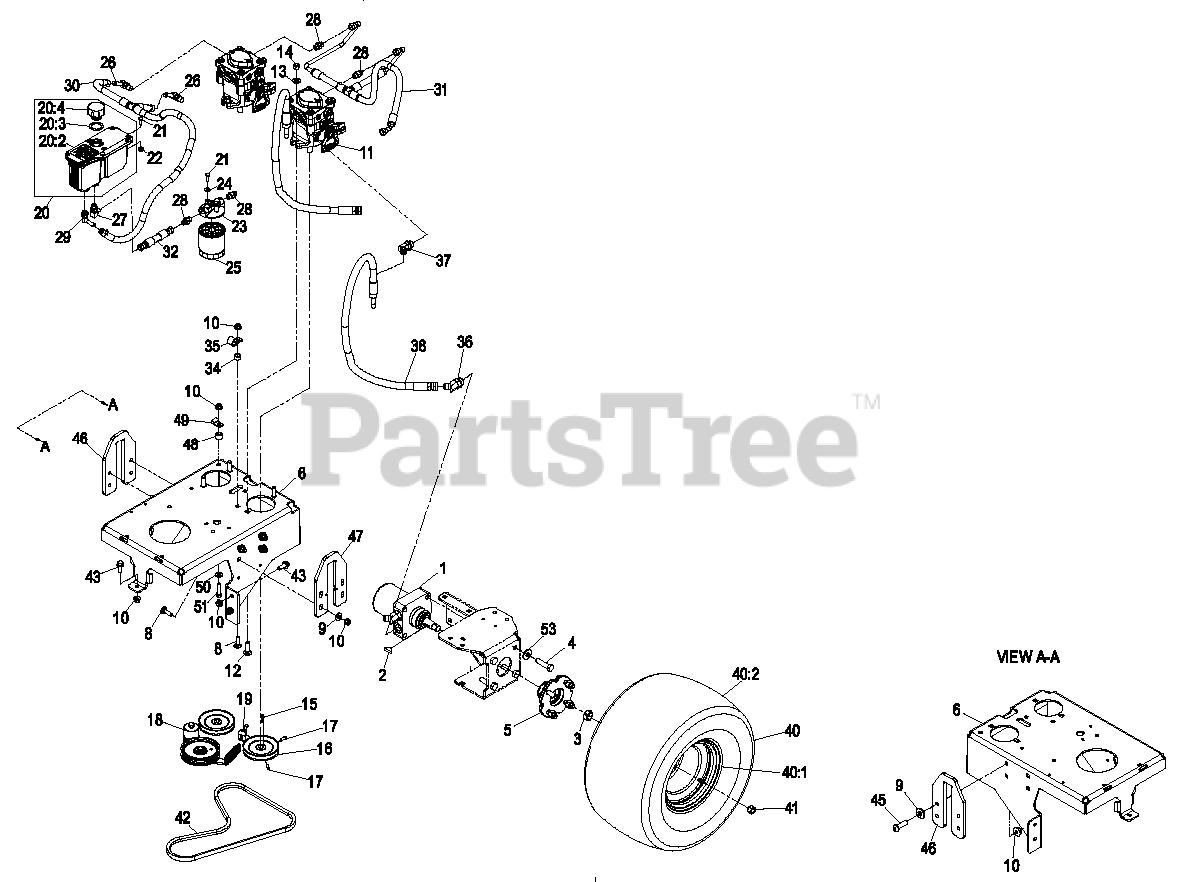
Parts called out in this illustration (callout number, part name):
1	HYD MOTOR ASM
2	KEY-WOODRUFF
3	NUT-MOTOR, WHEEL
4	SCREW-HH
5	WHEEL HUB ASM
6	BASE-ENGINE
8	BOLT-CARR
9	WASHER-BELLEVILLE
10	NUT-HF, NI
11	PUMP - HYDRAULIC
12	SCREW-HH
13	WASHER-FLAT
14	NUT-LOCK, NI
16	PULLEY-PUMP
17	SCREW-SET
18	PUMP IDLER ASM
19	BRACKET-ANCHOR, SPRING
20	RESERVOIR ASM
20:2	DECAL-HYDRAULIC TANK
20:3	GASKET-CAP
20:4	Cap-Reservoir, HYD
21	SCREW-HH
22	NUT-HHF
23	HEAD-FILTER
24	WASHER-FLAT
25	FILTER-25 MICRON, BI-DIRE
26	FITTING-ELBOW, 90
27	FITTING-ELBOW, 90 DEG
28	FITTING-STRAIGHT
29	FITTING-BARBED, 45 DEG
30	TANK HOSE ASM
31	HOSE ASSEMBLY - CHARGE
32	HYD HOSE ASM
34	SPACER-WHEEL
35	CLIP-LOOM
36	FITTING-HYD, 45 DEG
37	FITTING-HYD, 45 DEG
40	WHEEL ASM
40:1	RIM-8 INCH
41	NUT-LUG
42	BELT-V, LOWER PTO
43	SCREW-HHF 3/8-16 X 1
45	SCREW-HSBH
46	PLATE, LIFT RH
47	PLATE, LIFT LH
48	SPACER-PIVOT
49	CLIP-TUBE
50	WASHER-FLAT
51	SCREW-HH
53	WASHER-SPRING
